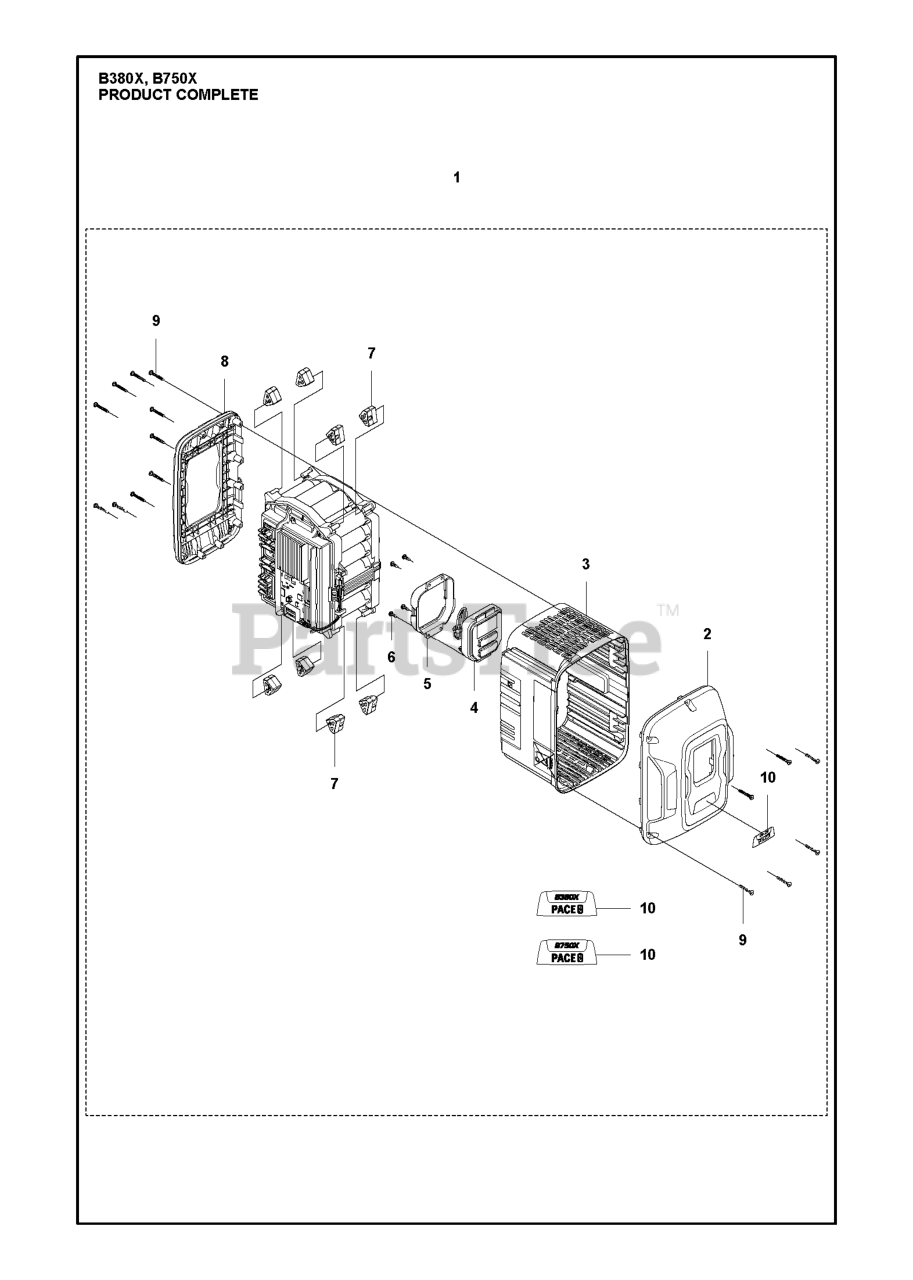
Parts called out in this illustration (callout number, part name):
2	COVER
3	HOUSING ASSY
4	CONTROL PANEL
8	COVER
9	SCREW
10	LOGOTYPE
